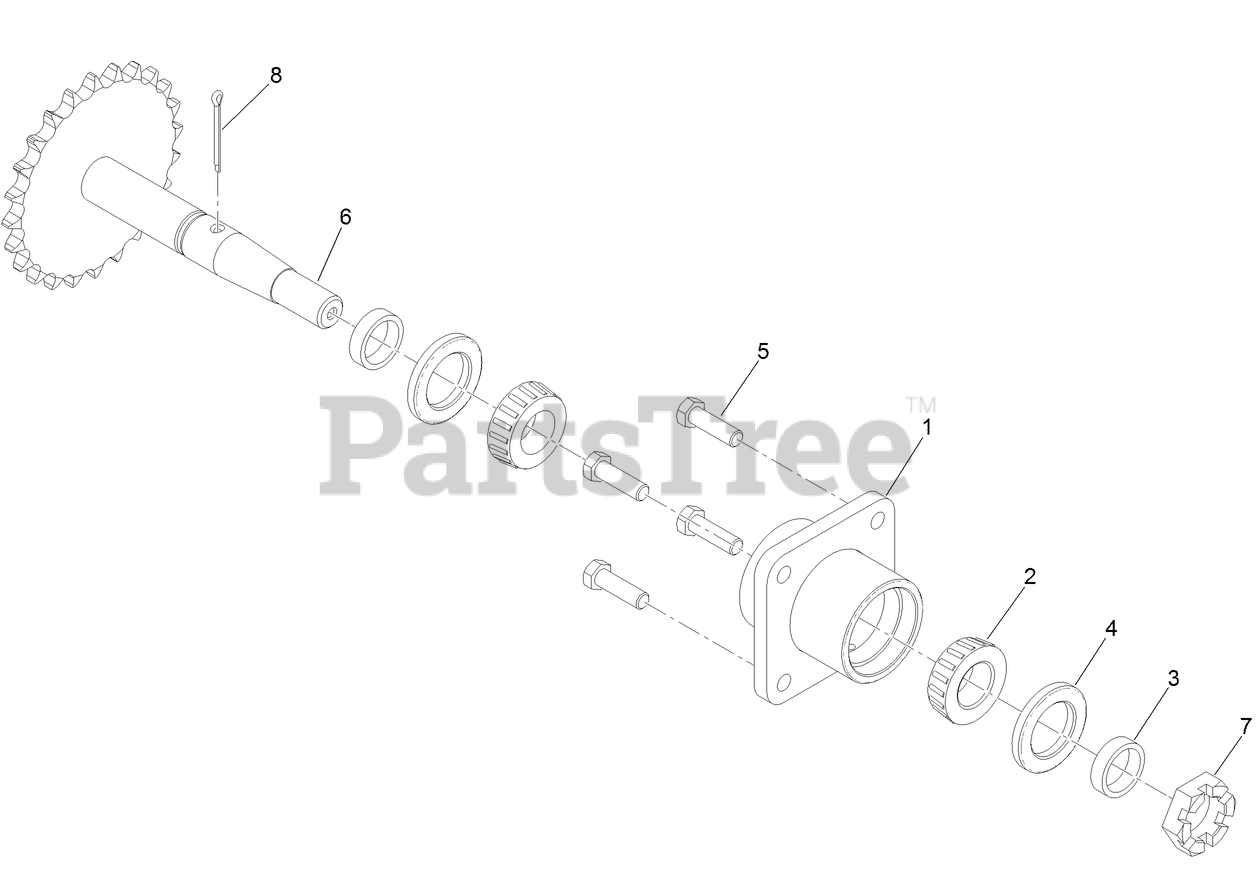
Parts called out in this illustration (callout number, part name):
1	MOUNT-BEARING, WHEEL
2	BEARING-ROLLER, TAPERED
3	SPACER
4	SEAL-GREASE
5	SCREW-HH
8	PIN-COTTER
